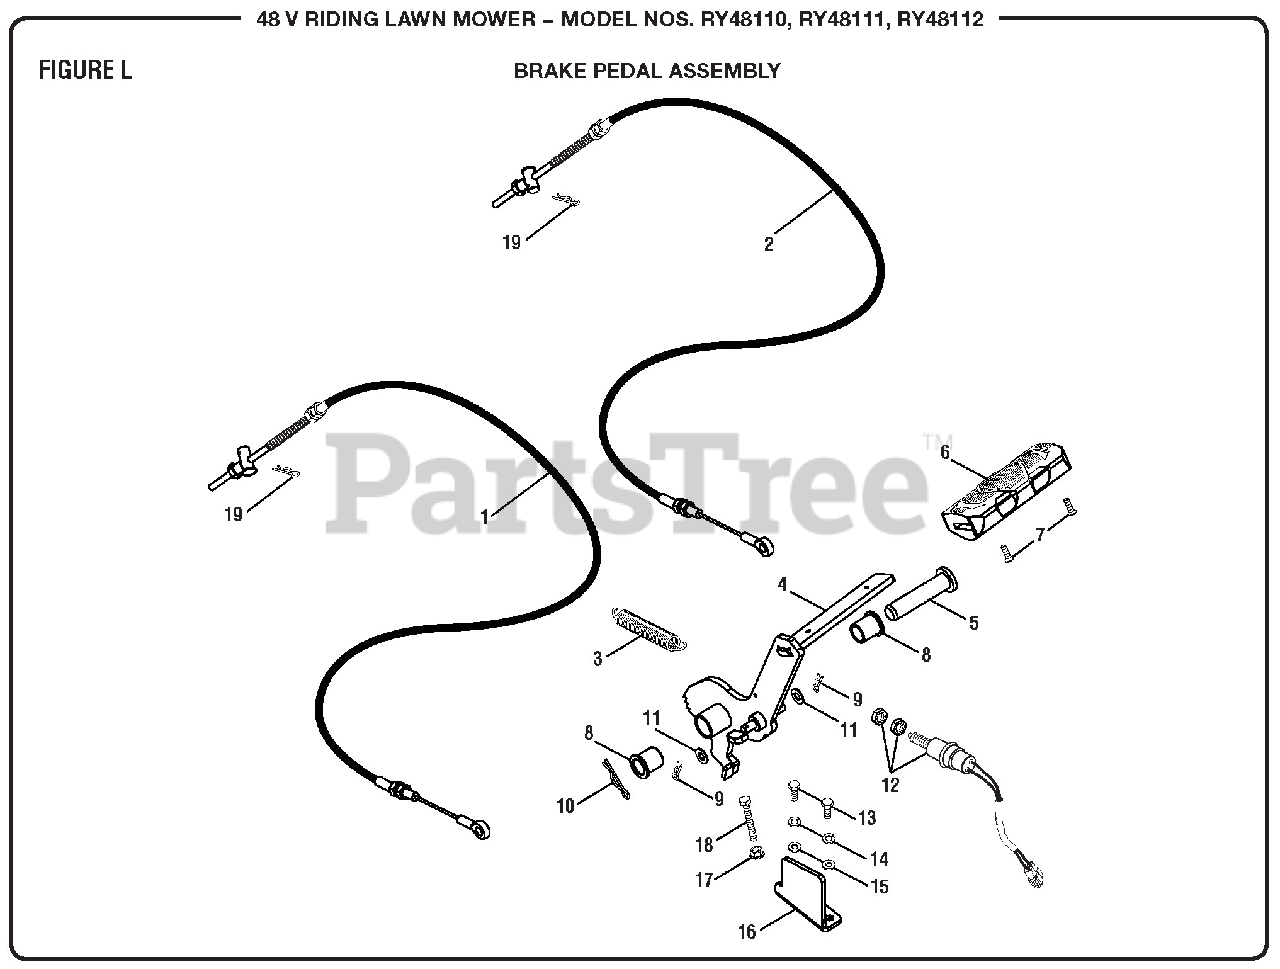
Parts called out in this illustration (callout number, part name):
1	Right Brake Cable
2	Left Brake Cable
3	Pedal Spring
5	Clevis Pin
6	Brake Pedal
7	Screw (M5 x 16 mm, Flat Hd.)
9	Lock Pin (8 mm)
10	Lock Pin (16 mm)
11	Washer (OD16 x ID8.4 x 1.6t)
12	Brake Switch Assembly
13	Bolt (M6 x 16 mm, Hex Hd.)
14	Spring Washer (M6)
15	Washer (OD12 x ID6.4 x 1.6t)
16	Brake Switch Guard
17	Flange Nut (M6)
18	Bolt (M6 x 45 mm, Hex Hd.)
